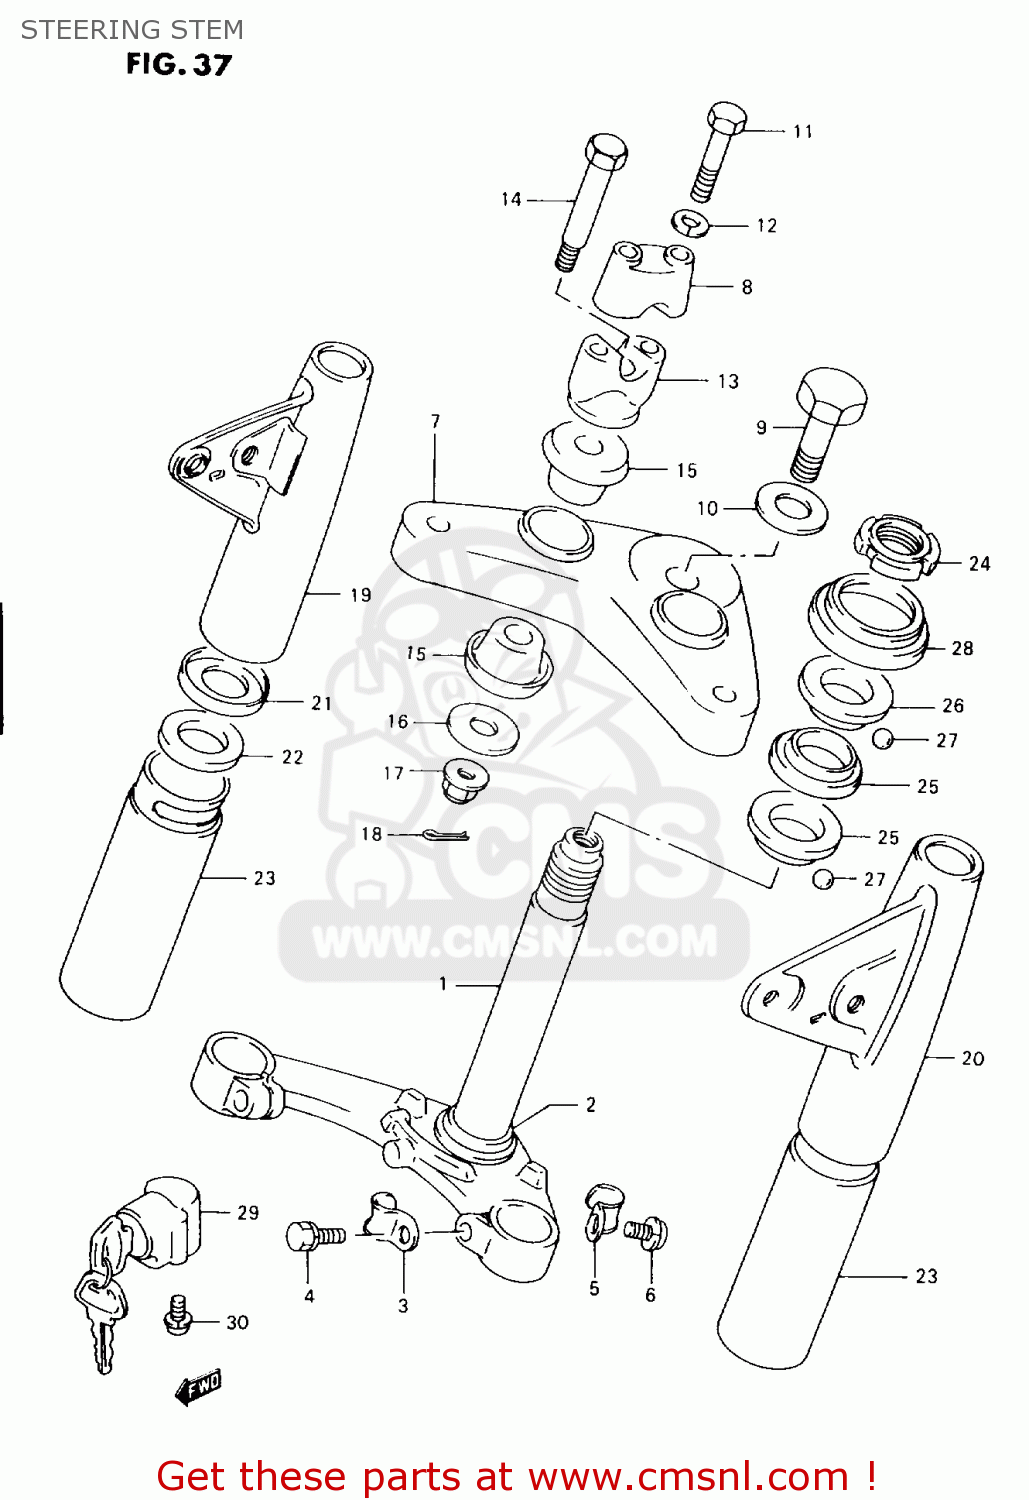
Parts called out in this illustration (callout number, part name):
1	STEM,STEERING
2	RACE,STEERING OUTER LWR
3	CLIP,SPEEDOMETER CABLE
4	BOLT
5	CLIP,BRAKE CABLE
6	SCREW
7	HEAD,STEERING STEM
8	HOLDER,HANDLEBAR
9	BOLT,FR FORK(10X33)
10	WASHER,STEM HEAD(10.5X30X3.2)
11	BOLT
12	WASHER,LOCK
13	HOLDER,HANDLE LWR
14	BOLT
15	DAMPER,RUBBER
16	WASHER
17	NUT
18	PIN 20X20
19	BRACKET, HEADLAMP RH (RED)
20	BRACKET,HEADLAMP,L
21	COVER,GUIDE
22	GASKET (NAS)
23	COVER,OUTER
24	NUT,STEERING STEM(25X44X10)
25	RACE,STEERING INNER UPR
26	RACE,STEERING OUTER UPR
27	BALL
28	DUST SEAL,STEERING UPR
29	LOCK ASSY,STEERING
30	SCREW
